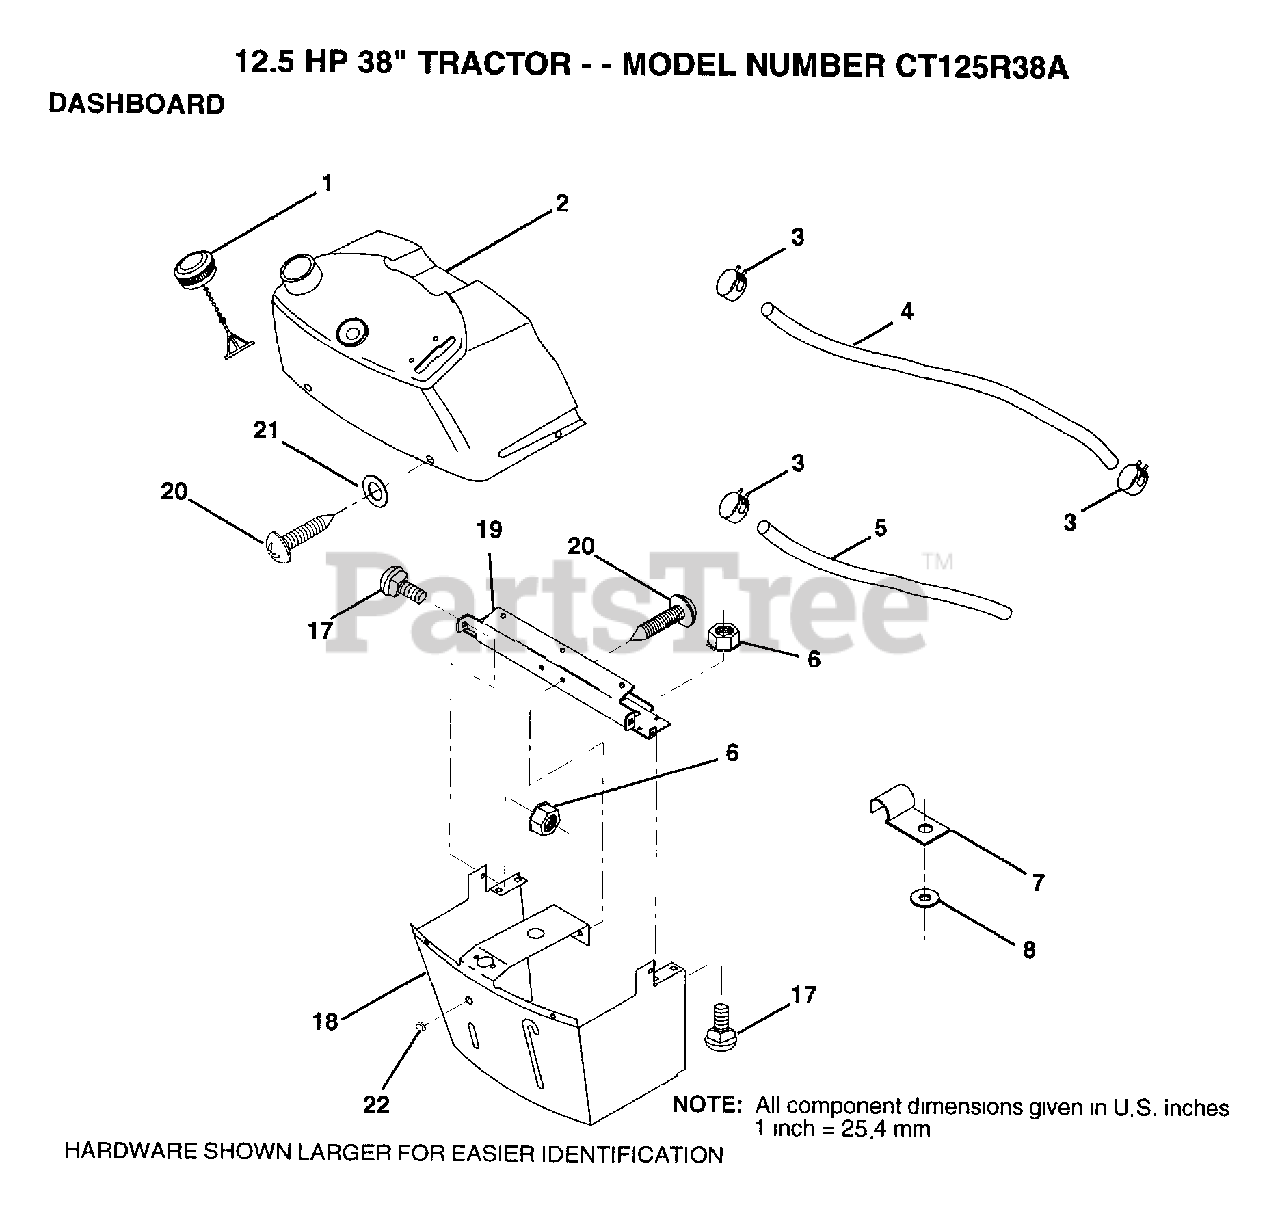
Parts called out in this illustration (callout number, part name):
1	CAP.FUEL.N/VENT
2	TANK.ASM.DASH.LR
3	HOSE CLAMP
5	FUEL LINE T
6	NUT
7	CLIP T
8	WASHER PM
17	BOLT
18	SUPT ASM DASH
19	CROSS BRACE
22	PLUG DOME
